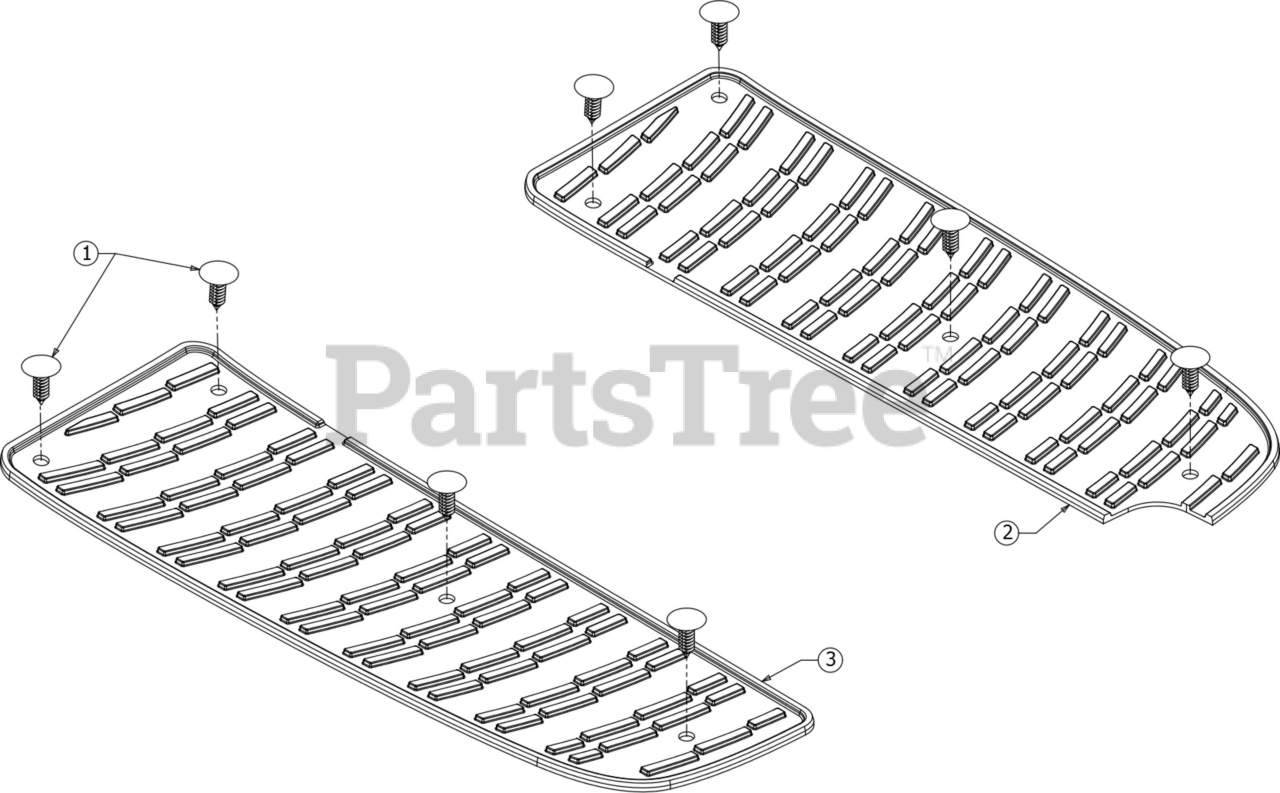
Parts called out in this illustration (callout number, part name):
1	RATCHET CLIP .250
2	RUNNING BOARD PAD (LH)
3	RUNNING BOARD PAD (RH)
